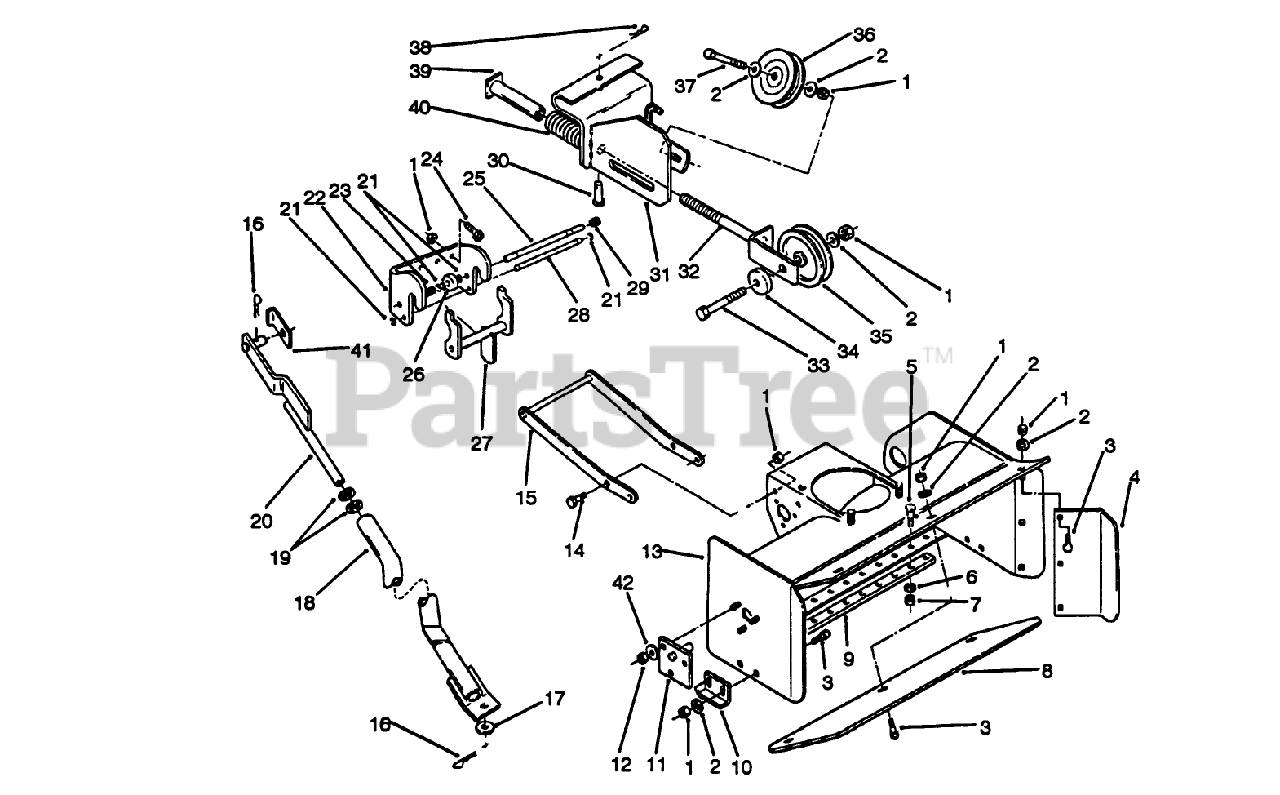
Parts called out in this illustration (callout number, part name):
1	NUT-LOCK, NI
2	WASHER-FLAT
3	BOLT-CARR
4	Plate
5	SCREW-CARR
6	WASHER-FLAT
7	NUT-LOCK, NI
8	Plate
9	Scraper
10	Skid
11	Plate
12	NUT-LOCK, NI
13	Wrapper
14	SCREW-HH
15	Mounting-Frame
16	PIN-COTTER
17	WASHER-FLAT
18	Tube-Lift
19	Washer
20	Rod-Lit
21	RING-RETAINING
22	Housing-Front Hitch
23	SPRING
24	SCREW-CARR
25	ROD-LOCK
27	Assy-Latch
28	ROD-LATCH PIVOT
29	CAP-ROD, PLUNGER
30	Clevis Pin
31	Bracket-Idler
32	IDLER-SLIDE W.A.
33	SCREW-HH
34	BUSHING
35	Pulley-Idler
36	"V" Pulley
37	SCREW-HH
38	PIN-HAIR
39	Spring-Torsion
40	Spring-Compression
41	RETAINER CLIP
42	WASHER-FLAT
